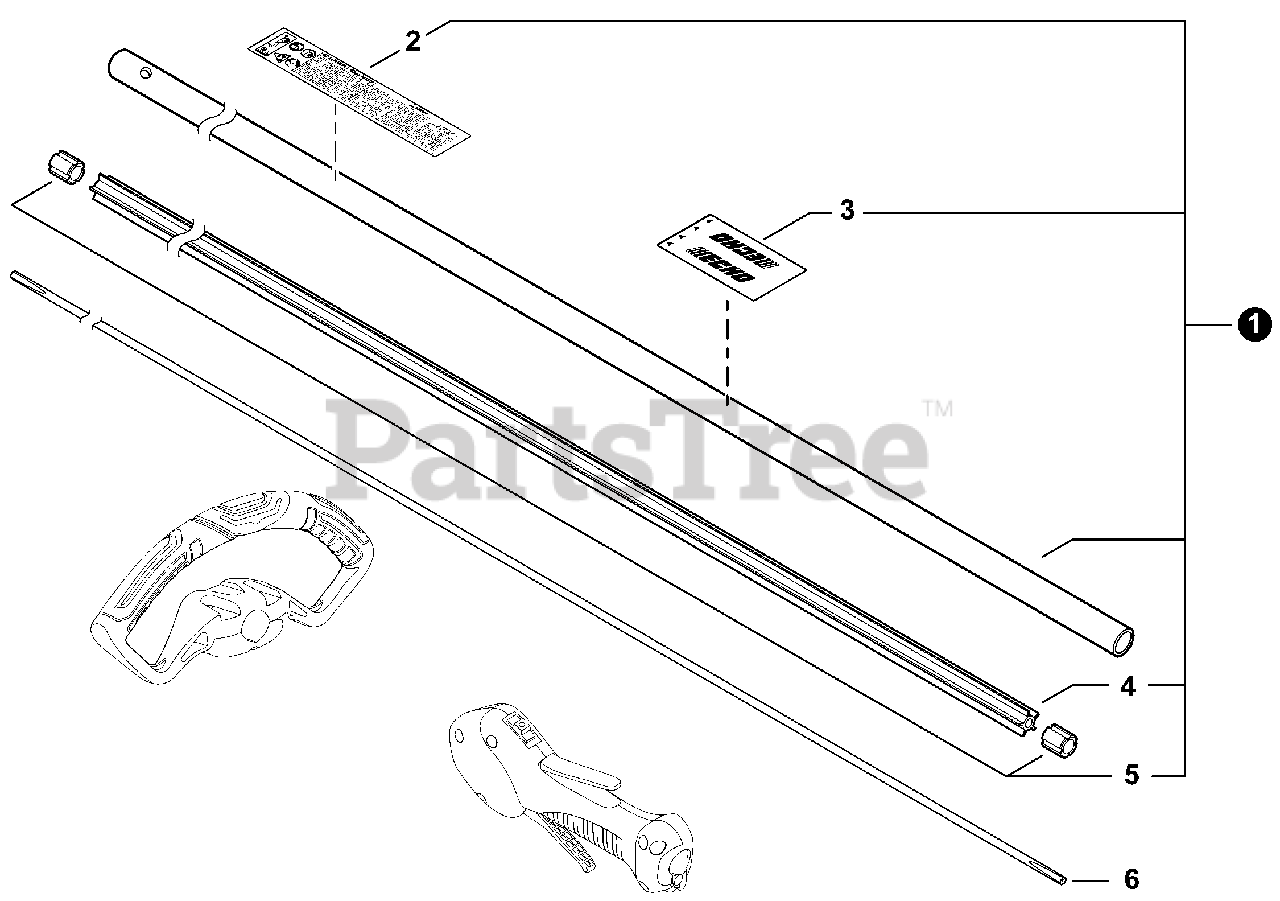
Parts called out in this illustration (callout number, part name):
1	MAIN PIPE ASSY
2	LABEL - CAUTION
3	LABEL - HANDLE LOCATION
4	LINER, FLEXIBLE 21.6x1420
6	DRIVESHAFT - FLEXIBLE
